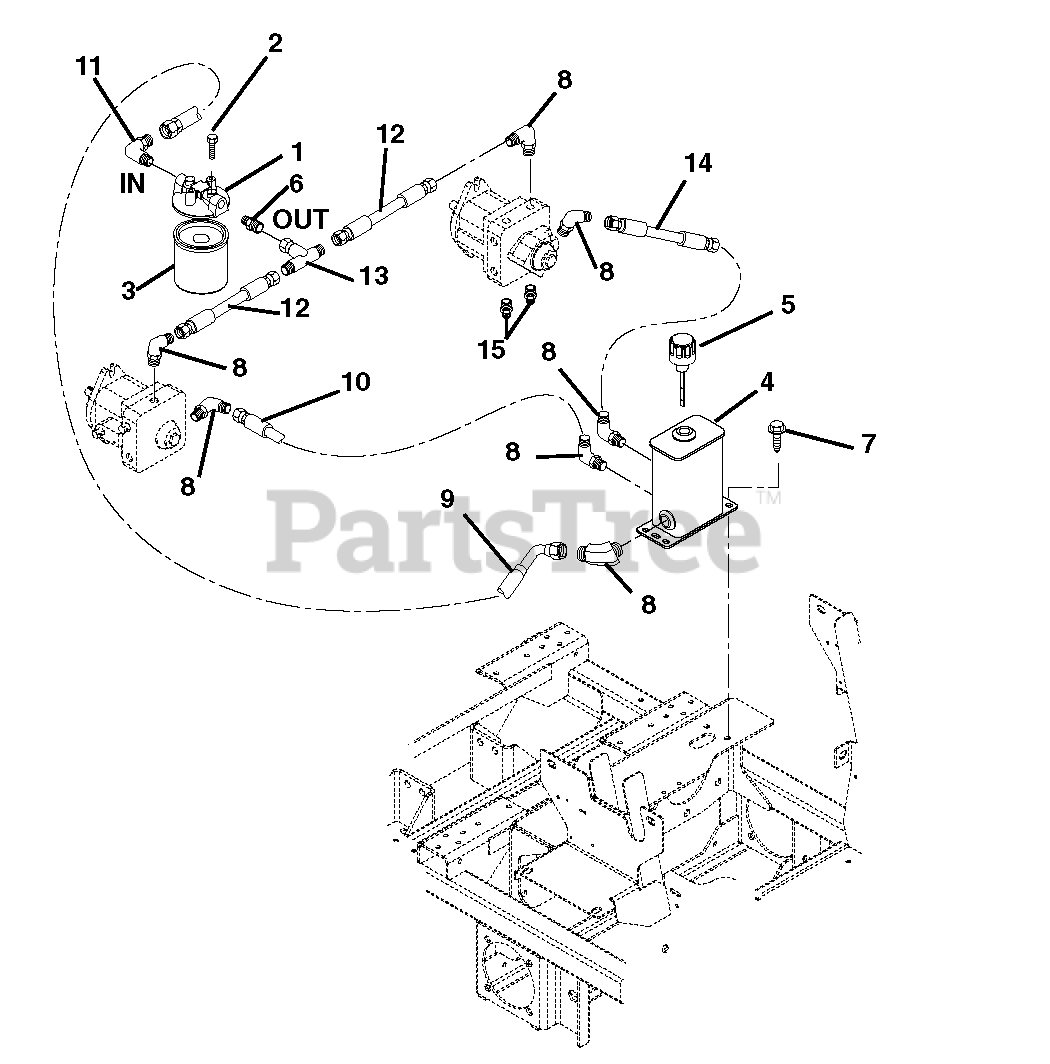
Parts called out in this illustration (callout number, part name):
1	Head, Filter
2	Bolt, Hex .25-20 x .50 Grade 5 Epoxy
3	Oil Filter
4	Weldment,Formed 3-Port
5	Hydraulic Tank Dipstick
6	Fitting, Hydraulic, Straight
7	Screw, Tapping .38-16 x .75 Hex Washer Head
8	Fitting, Hydraulic, 90 Degree Elbow
9	Hose, Hydraulic Valve to Tank
10	Hose, Hydraulic, 10-inch
11	Fitting, Hydraulic, 90 Degree Elbow
12	Hose, Hydraulic .50, 5-Inch
13	Fitting, Hydraulic Tee
14	Hose, Hydraulic
15	Fitting, Hydraulic (4 F5OLO)
